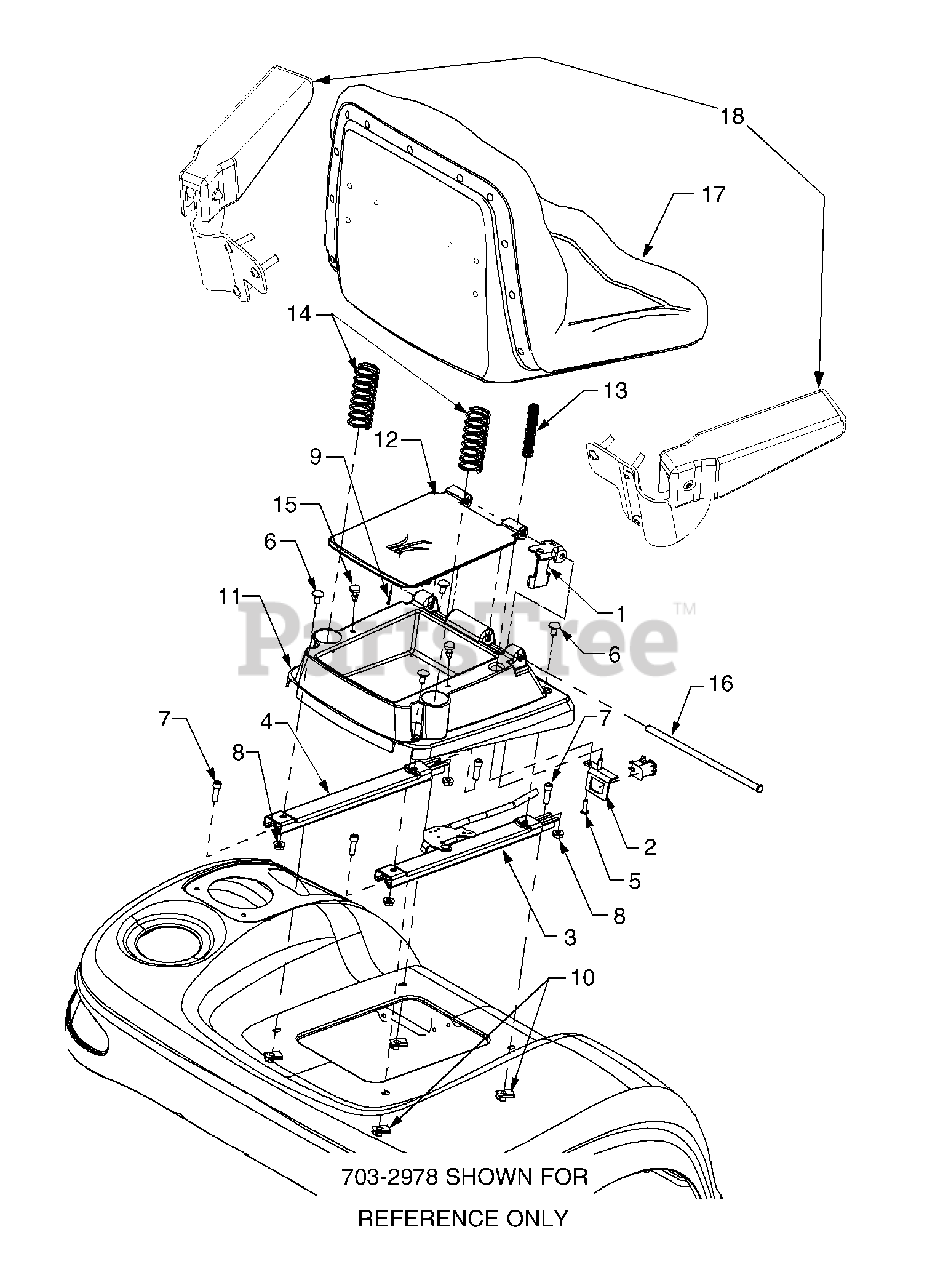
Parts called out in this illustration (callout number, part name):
1	Bracket, Seat Switch
2	Bracket, Switch Mounting
3	Track, Seat, w/Latch
4	Track, Seat, w/o Latch
5	Screw, Pan Torx Hd., #12-14 x .5
6	Carriage Bolt, 5/16-18 x .62
7	Screw, Pan Torx Hd. 5/16-18 x 1.0
8	Nut, Hex Flange Lock, 5/16-18
9	Pin, Cotter, 3/32 x .75
10	Speed Nut, U-Type, 5/16-18
11	Base, Seat
12	Lid, Tlbx
13	Spring, Compression
14	Spring, Compression
15	Bumper
16	Rod, Seat Pivot
17	Seat, High Back
18	Armrest, Seat - Set
